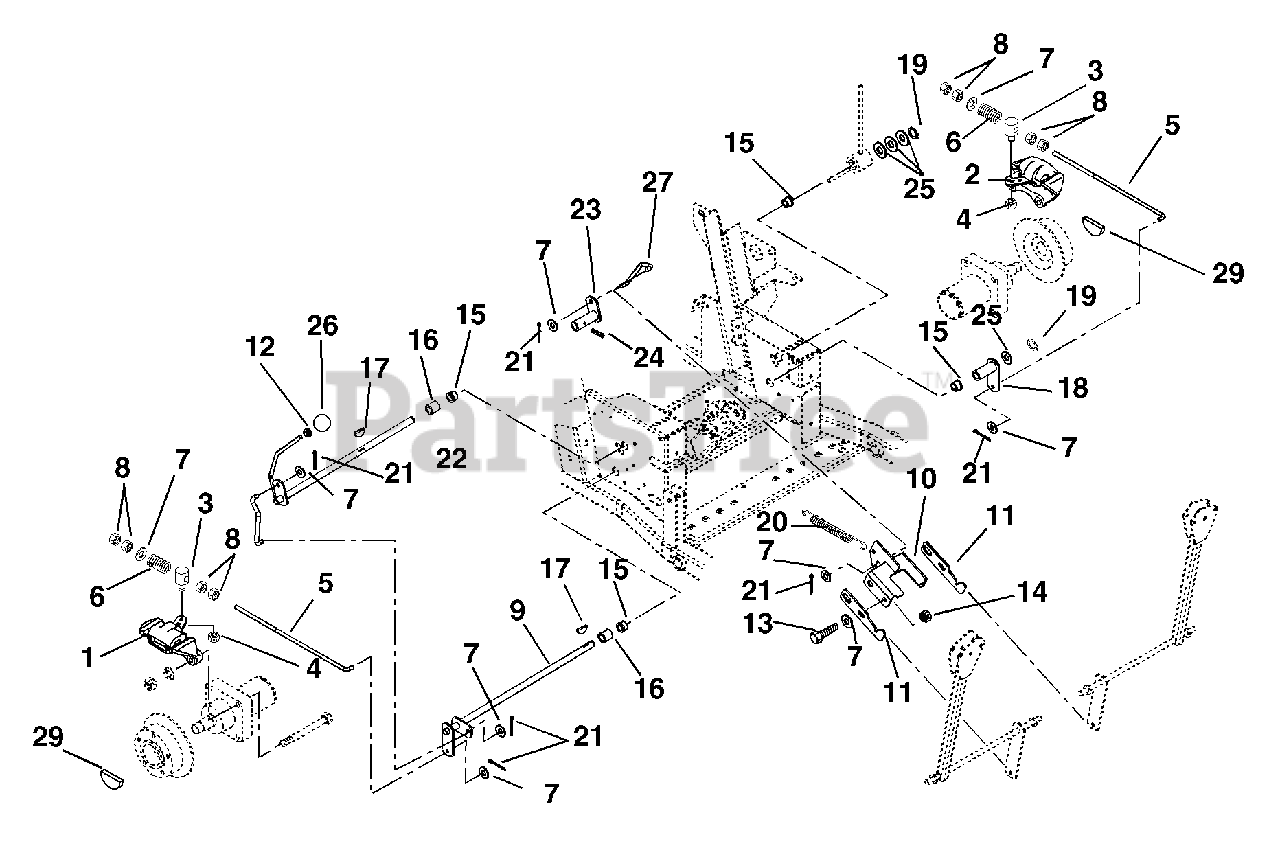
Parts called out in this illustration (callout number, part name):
1	Caliper, Park Brake (CW) Right Hand
2	Caliper, Park Brake (CCW) Left Hand
3	Pivot-Brake Rod
4	Nut-Locking-Center .31-18
5	Rod-Brake 12 inch
6	Spring-Compression .143 x .710 x 2.00
7	Washer-Flat-Steel .406 x .812 x .065
8	Nut-Hex .38-16
9	Shaft-Brake Cross
10	Interlock-Fixed
11	Interlock-Adjustable
12	Nut-Hex-Jam .375 -16
13	Bolt-Hex .38-16 x 1.00 Grade 5
14	Nut-Locking-Center .38-16
15	Bushing-Flange .630 x 1.000 x .625
16	Spacer .630 x .878 x 1.000
17	Key-Woodruff .19 x .75 Hard #9
18	Arm-Brake Left-Hand
19	Ring-Retaining-External .625 x .050
20	Spring-Tension .105 x .85 x 5.00
21	Pin-Cotter External .09 x .75
22	Shaft-Brake Actuating
23	Actuator
24	Pin-Roll .125 x 1.00
25	Washer-Flat-Steel .627 x .990 x .032
26	Knob-Steering Lock
27	Rod-Brake Actuating
28	Pin-Cotter-External .09 x .75 r
29	Pad, Disk Brake
